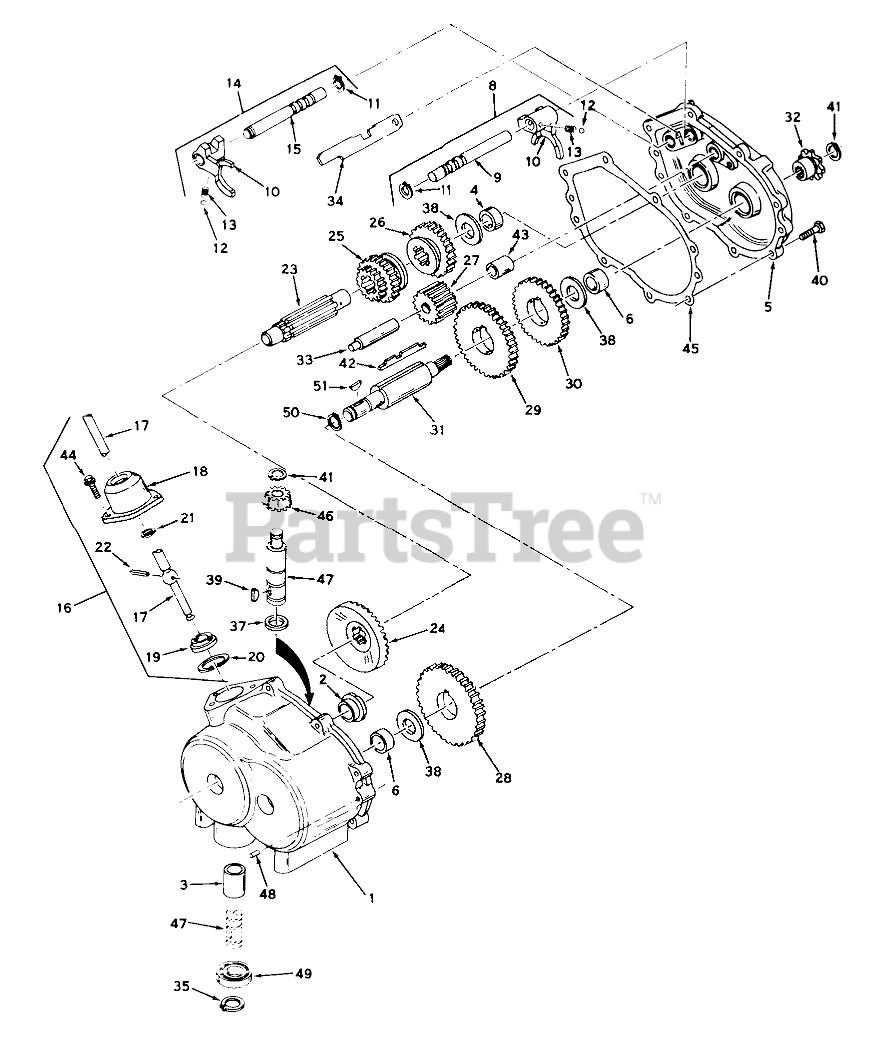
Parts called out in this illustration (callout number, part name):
1	Case Assy., Transmission (Incl. Nos. 2, 3 & 6)
2	Bearing, Bronze
3	Bearing, Bronze
4	Bearing, Bronze
5	Cover Assy., Transmission (Incl. Nos. 4 & 6)
6	Bushing, Bronze
8	Rod Assy., Shift (Incl. Nos 9 thru 13)
9	Shift Rod
10	Shift Fork
11	Ring-Snap
12	Piston ASM
13	Spring
14	Rod Assy., Shift (Incl. Nos. 10 thru l3 & 15)
15	Rod, Shift
16	Lever & Housing Assy., Shift (Incl. Nos. 17 thru 22)
17	Lever, Shift
18	Shift Lever Housing
19	Keeper-Shift Lever
20	Ring-Snap
21	O Ring
22	Roll Pin
23	Shaft, Shifter
24	Gear, Bevel (33 teeth)
25	Gear, Shift 1st & 2nd)
26	Gear, Shift 3rd & Rev.)
27	Idler, Reverse
28	Gear (39 teeth)
29	Gear (34 teeth)
30	Gear (30 teeth)
31	Shaft, Output
32	Sprocket (8Teeth)
33	Shaft, Reverse Idler
34	Stop, Shifter
35	Ring-Snap
37	Bearing, Thrust
38	Washer
39	Key, Woodruff
40	Screw-Thread Forming
41	Ring-Retainer
42	Key, Countershaft
43	Reverse Idler Spacer
44	Screw
45	Gasket, Transmission
46	Pinion, Input
47	Shaft, Input
48	Dowel Pin
49	Bearing-Ball
50	Snap Ring
51	Kev. Woodruff
